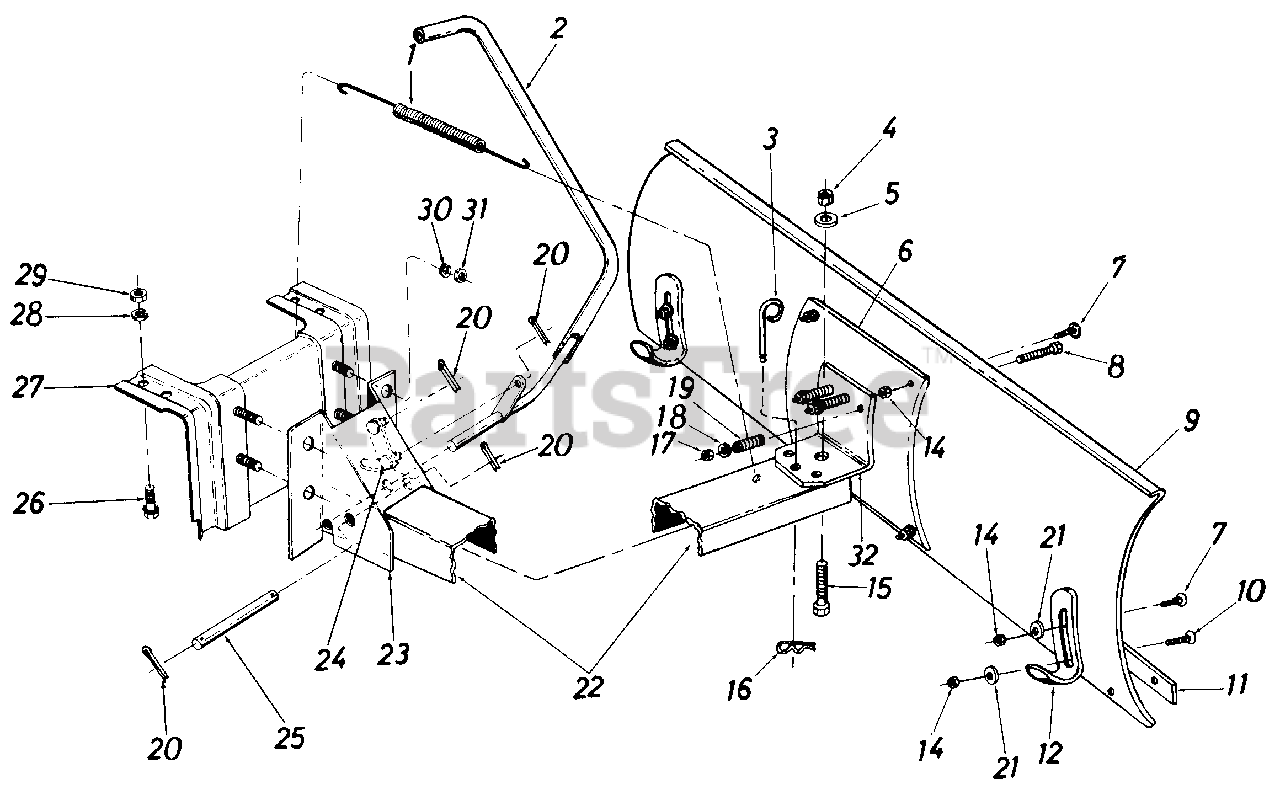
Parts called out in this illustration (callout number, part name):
1	Extension Spring
2	Lift Handle Ass'y.
3	Pivot Lock Pin
4	Hex Cent. L.-Nut 1/2-13 Thd.
5	Fl.-Wash. 17/32 I.D. x 1.25" Lg.
6	Reinforcement Plate
7	Carriage Bolt 5/16-18 x .75" Lg.*
8	Hex Scr. 3/8-16 x 3.75" Lg. Grade 5
9	42" Blade
10	Carriage Bolt 5/16-18 x 1.00" Lg.*
11	42" Wear Plate
12	Shoe Skid
14	Hex Cent. L.-Nut 5/16-18 Thd.*
15	Hex Scr. 1/2"-13 x 1.25" Lg.*
16	Hair Pin Cotter
17	Hex Cent. L.-Nut 3/8-16 Thd.
18	Fl.-Wash. 3/8" I.D.
19	Compression Spring
20	Cotter Pin 1/8" Dia. x 1.00" Lg.*
21	Fl.-Wash. 5/16" Scr.
22	Push Bar Channel
23	Pivot Support Bracket
24	Lift Link
25	Channel Pivot Shaft
26	Hex Scr. 5/16-18 x 1.00" Lg. Grade 5
27	Support Bracket Ass'y.
28	L.-Wash. 5/16" Scr.*
29	Hex Nut 5/16-18 Thd.*
30	L.-Wash. 3/8" Scr.*
31	Hex Nut 3/8-16 Thd.
32	Support Bracket
